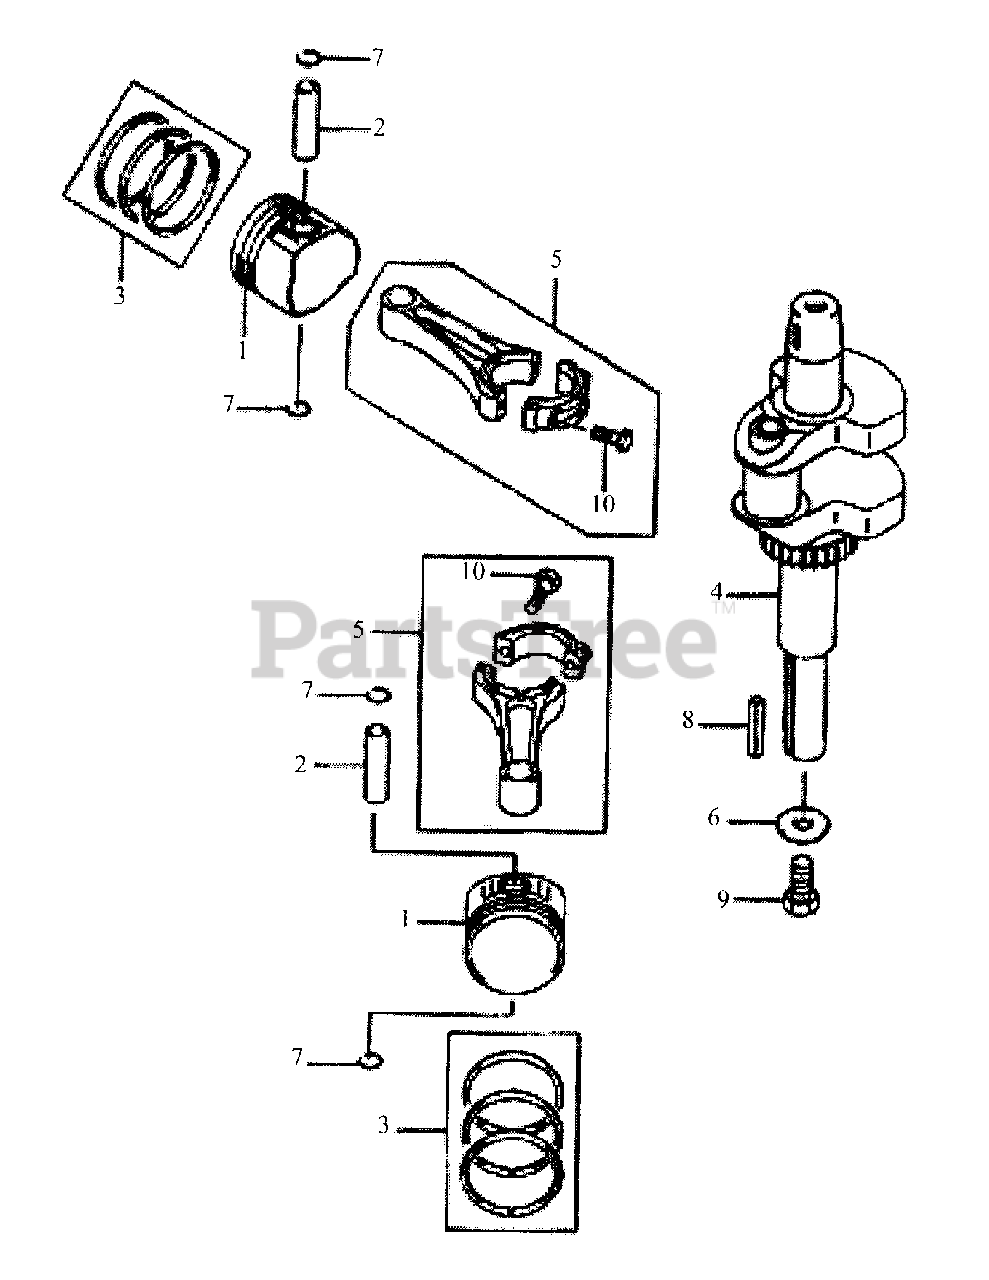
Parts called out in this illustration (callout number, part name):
1	Piston, Engine
2	Pin, Piston
3	Ring-Set, Piston
4	Crankshaft
5	Rod-Connecting
6	Washer 12.5020.2
7	Ring-Snap
9	Bolt,7/16-20UNF
10	Bolt,Flange
